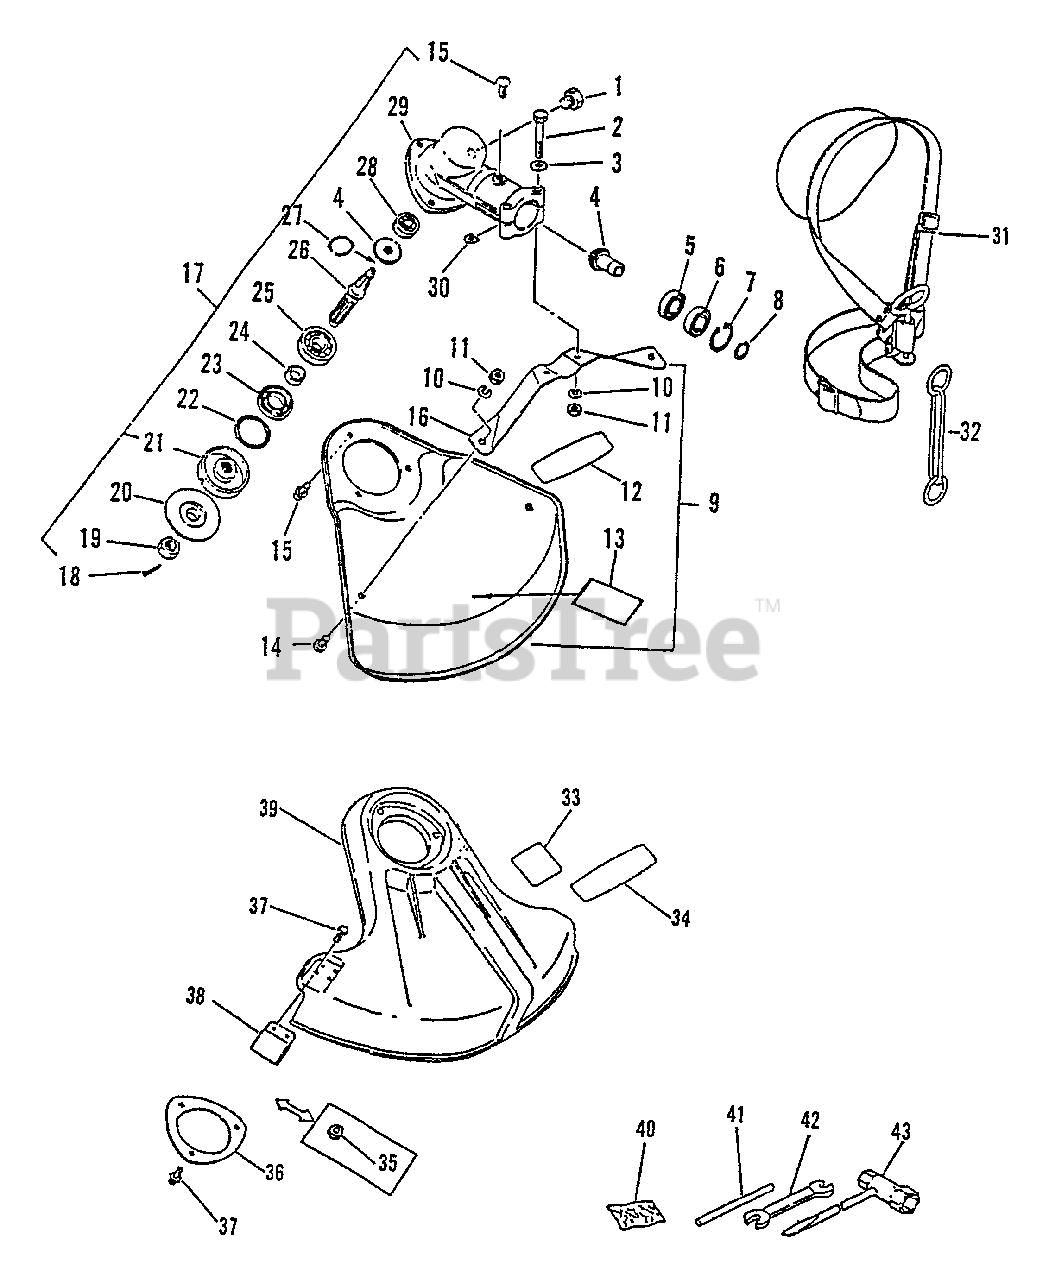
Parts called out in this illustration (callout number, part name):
1	BOLT 8×8 SP
2	BOLT 5×35 SP
3	WASHER, FLAT 5.5×10×0.8
4	GEAR SET
5	BEARING, BALL 6900
6	BEARING, BALL 6900Z
7	RING, SNAP Ø22
8	RING, SNAP Ø12
9	SHIELD ASSY
10	WASHER, SPRING 5
11	NUT M5
12	LABEL, ECHO
13	LABEL, CAUTION
14	SCREW 5×8
15	SCREW 5×10
16	BRACKET, SHIELD MOUNTING
17	GEAR CASE ASSY
18	PIN, COTTER 2×22
20	PLATE, ADAPTOR - LOWER
21	PLATE, ADAPTER - UPPER
22	RING, SNAP Ø32
23	SEAL, OIL 22
24	SPACER 11.8×15×9
25	BEARING, BALL - 6201 C3
26	SHAFT, GEAR
27	RING, SNAP Ø10
28	BEARING, BALL 609
29	HOUSING, GEAR CASE
31	SHOULDER STRAP ASSY
32	HOOK
33	LABEL, CAUTION
34	LABEL, ECHO
35	NUT M5
36	PLATE, SHIELD Ø49.5 MM
37	SCREW 5×16
38	CUTTER, LINE
39	DEBRIS SHIELD ASSY
40	PIN, COTTER 2×22 (PKG. OF 10)
41	TOOL, LOCKING 5×120 MM
42	SPANNER 8×10
43	T-WRENCH 17x-19 L200
